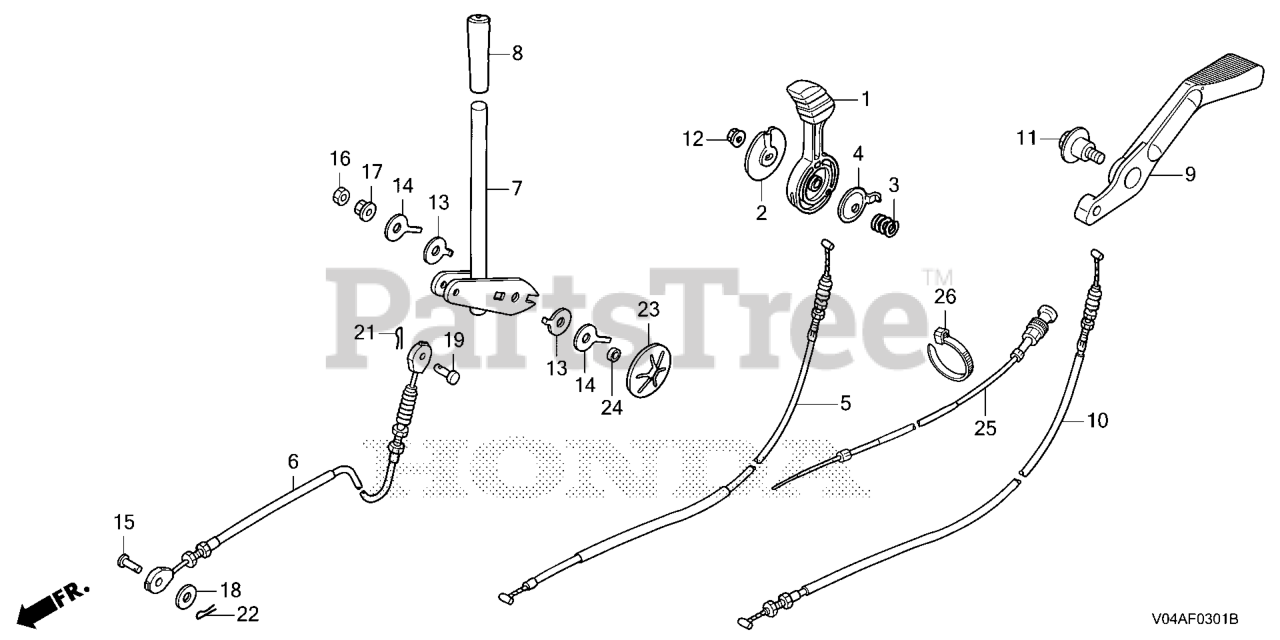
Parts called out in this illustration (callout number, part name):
1	LEVER, THROTTLE
2	PLATE, THROTTLE LEVER
3	SPRING, THROTTLE LEVER
4	SEAT, SPRING
5	CABLE, THROTTLE
5	CABLE COMP, THROTTLE
6	CABLE, CHANGE
7	LEVER, CHANGE
8	GRIP, CHANGE LEVER (ORANGE)
9	LEVER, HEIGHT ADJUSTING
10	CABLE, HEIGHT ADJUSTING
11	BOLT, SPECIAL (8X22)
12	NUT, NYLON LOCK (6MM)
13	WASHER, FRICTION
14	WASHER, FRICTION SETTING
15	PIN (8X34)
16	NUT, HEX. (8MM)
17	NUT-WASHER (8MM)
18	WASHER, PLAIN (8MM)
21	PIN, COTTER (1.6X12)
22	PIN, SPLIT
23	SPRING, ADJUSTING ARM
24	TUBE, RUBBER (7.3X12.5X5.5)
25	CABLE, CHOKE
